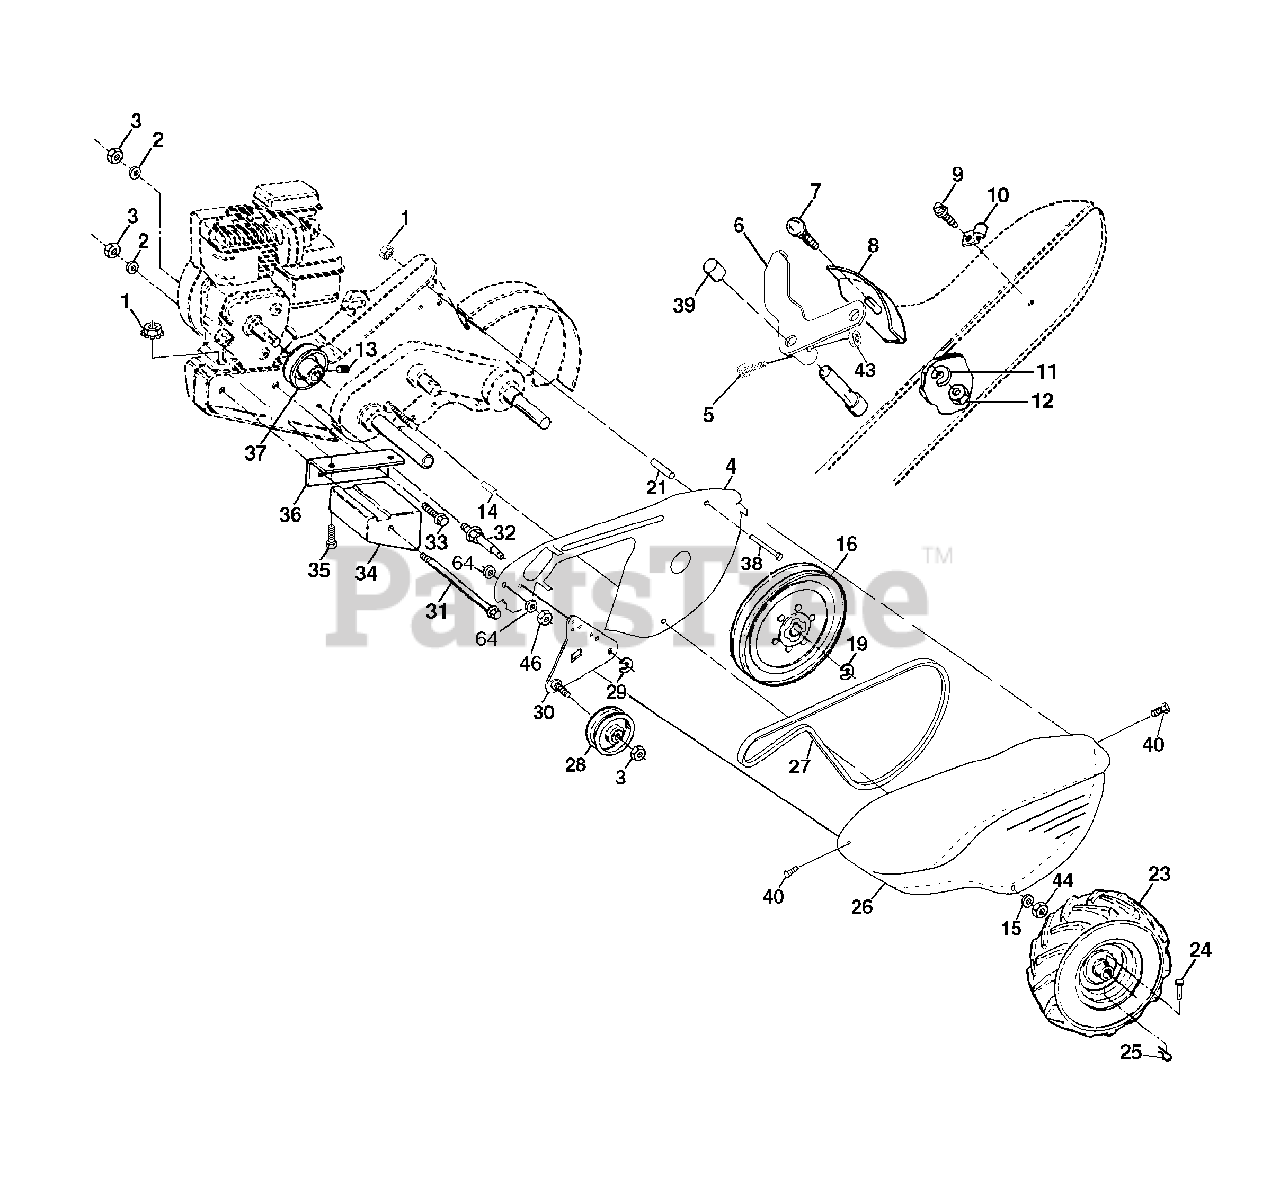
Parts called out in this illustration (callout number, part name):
1	Nut, Keps 5/16-18
2	Washer, Lock 3/8
3	Nut, Hex 3/8-16
4	Shield, Inner Belt Guard
5	Screw, Shift Lever
6	Lever, Shift
7	Bolt, Carriage 1/4-20 x 1/2 Gr. 5
8	Plate, Shift Indicator
9	Screw, Hex, Washer Head, Slotted #10-24 x 1/2
10	Clip
11	Washer, Lock 1/4
12	Nut, Hex 1/4-20
13	Screw, Set, Hex 5/16-18 x 3/8
14	Spacer, Split 0.327 x 0.42 x 1.220
15	Washer 11/32 x 11/16 x 16 Ga.
16	Sheave, Transmission
19	Ring, Retainer
21	Spacer, Split 0.327 x 0.42 x 2.09
22	Bolt, Fin Hex 5/16-24 x 1/2
23	Tire
23	Tire Valve
24	Rivet, Drilled
25	Clip, Hairpin
26	Guard, Belt
27	Belt, V
28	Pulley, Idler
29	Ring, Klip
30	Bracket, Idler
31	Bolt, Hex 5/16-16 x 12
32	Shaft, Idler Arm
33	Bolt, Hex 3/8-16 x 1
34	Counterweight, L. H.
35	Bolt, Hex 5/16-18 x 1-1/2
36	Bracket, Reinforcement, L. H.
37	Sheave, Engine
38	Bolt, Fin Hex 5/16-18 x 2-3/4
39	Cap, Plunger
40	Screw Hex Wsh Slt #10-24 x .50
43	Nut, Lock #10-24
44	Nut, Lock 5/16-18
